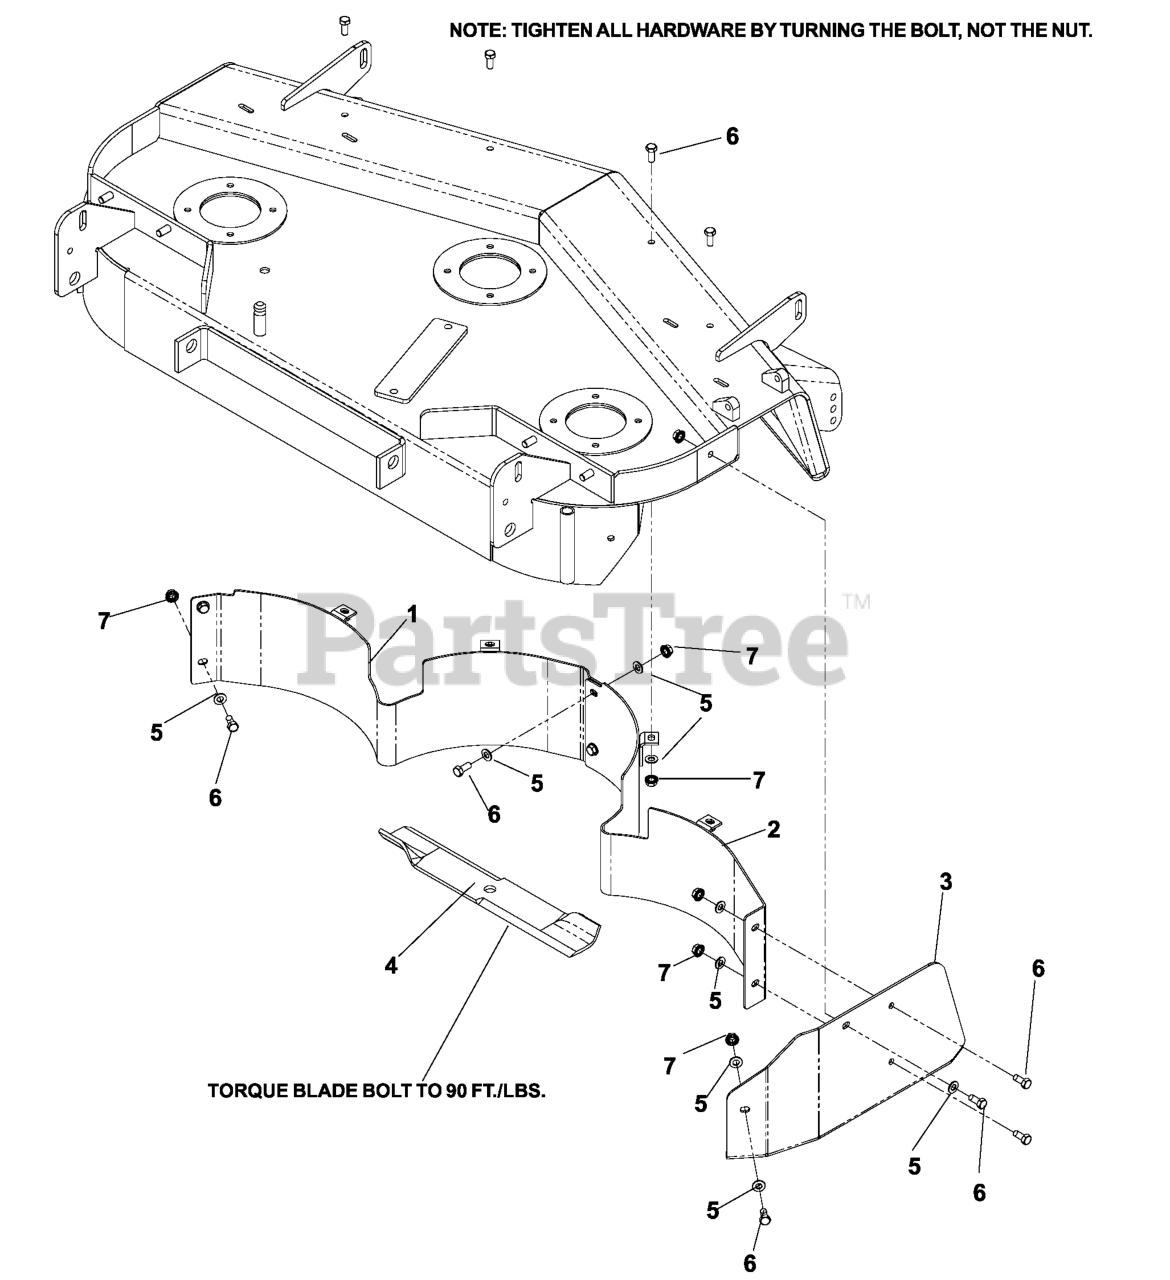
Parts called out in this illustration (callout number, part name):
1	MULCH BAFFLE, LEFT, 42
2	BAFFLE WLDMT, 42" R.H. MULCH
3	MULCH CAP 42"
4	BLADE, MULCH, 14 5/8"
5	FLAT WASHER 5/16 SAE
6	HCS 5/16C X 3/4
7	NUT 5/16C WHIZ
